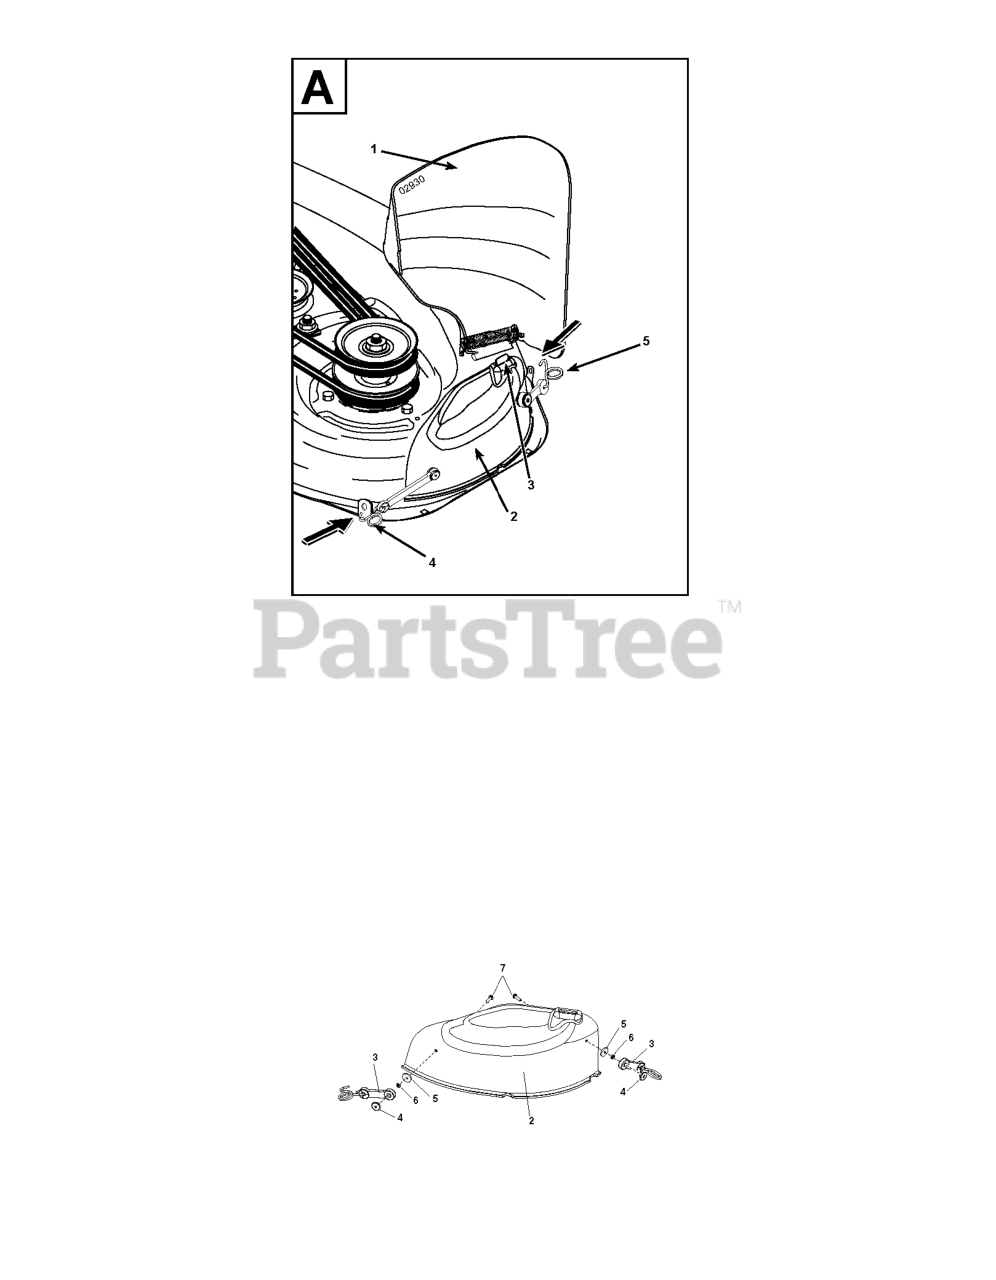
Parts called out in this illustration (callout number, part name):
2	COVER.ASM.MULCH/HDW.46"
3	LATCH ASSY
4	WELDNUT
6	LOCKWASHER #10
7	SCREW
